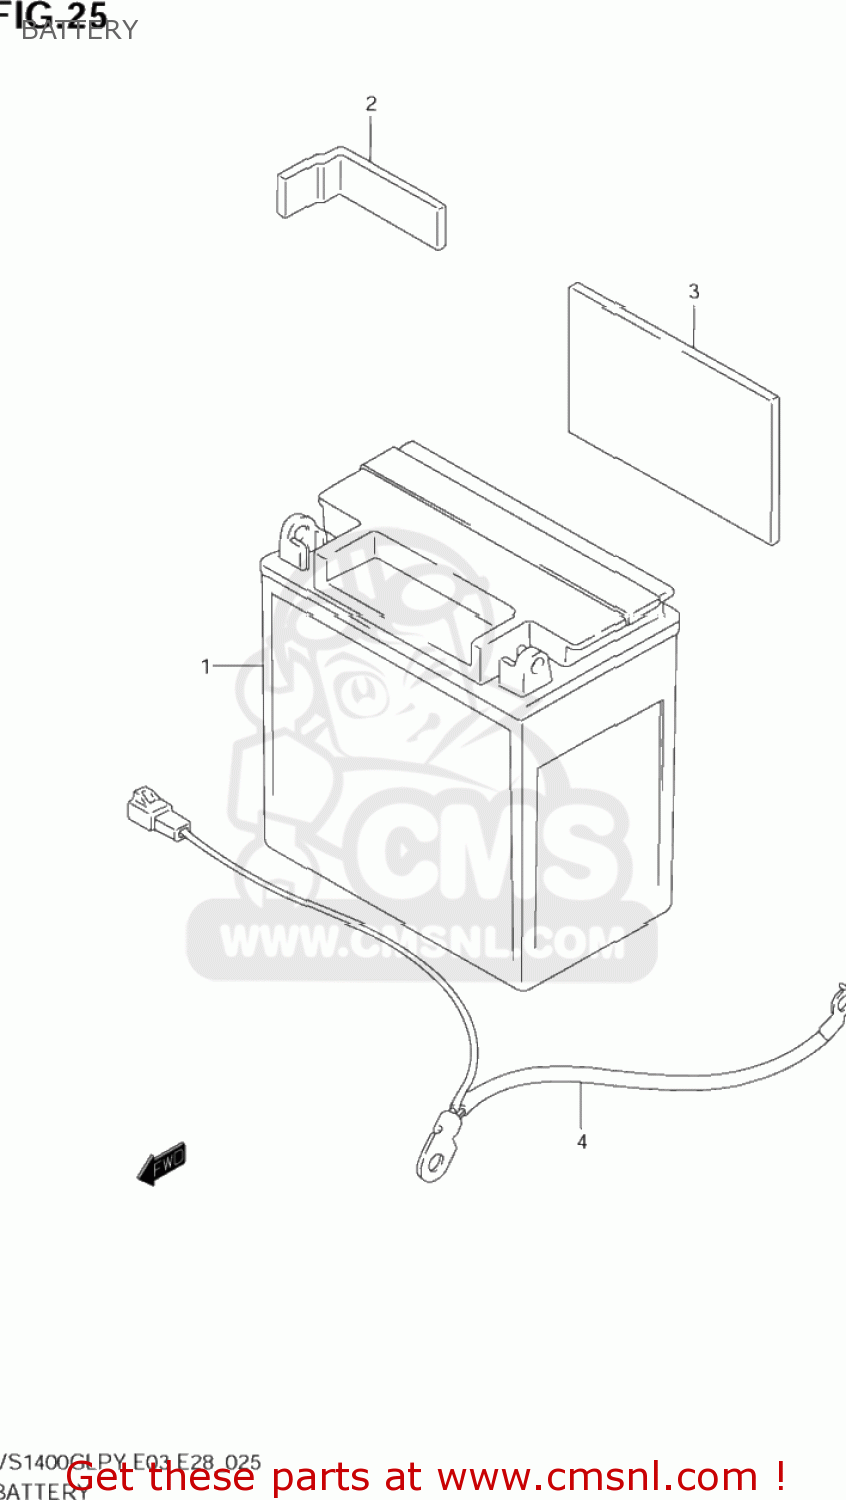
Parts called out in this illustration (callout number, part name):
1	BATTERY ASSEMBLY 12V14AH,F
2	PROTECTOR(80X80X2)
3	PROTECTOR(170X95X3.0)
4	WIRE,BATTERY MINUS LEAD
